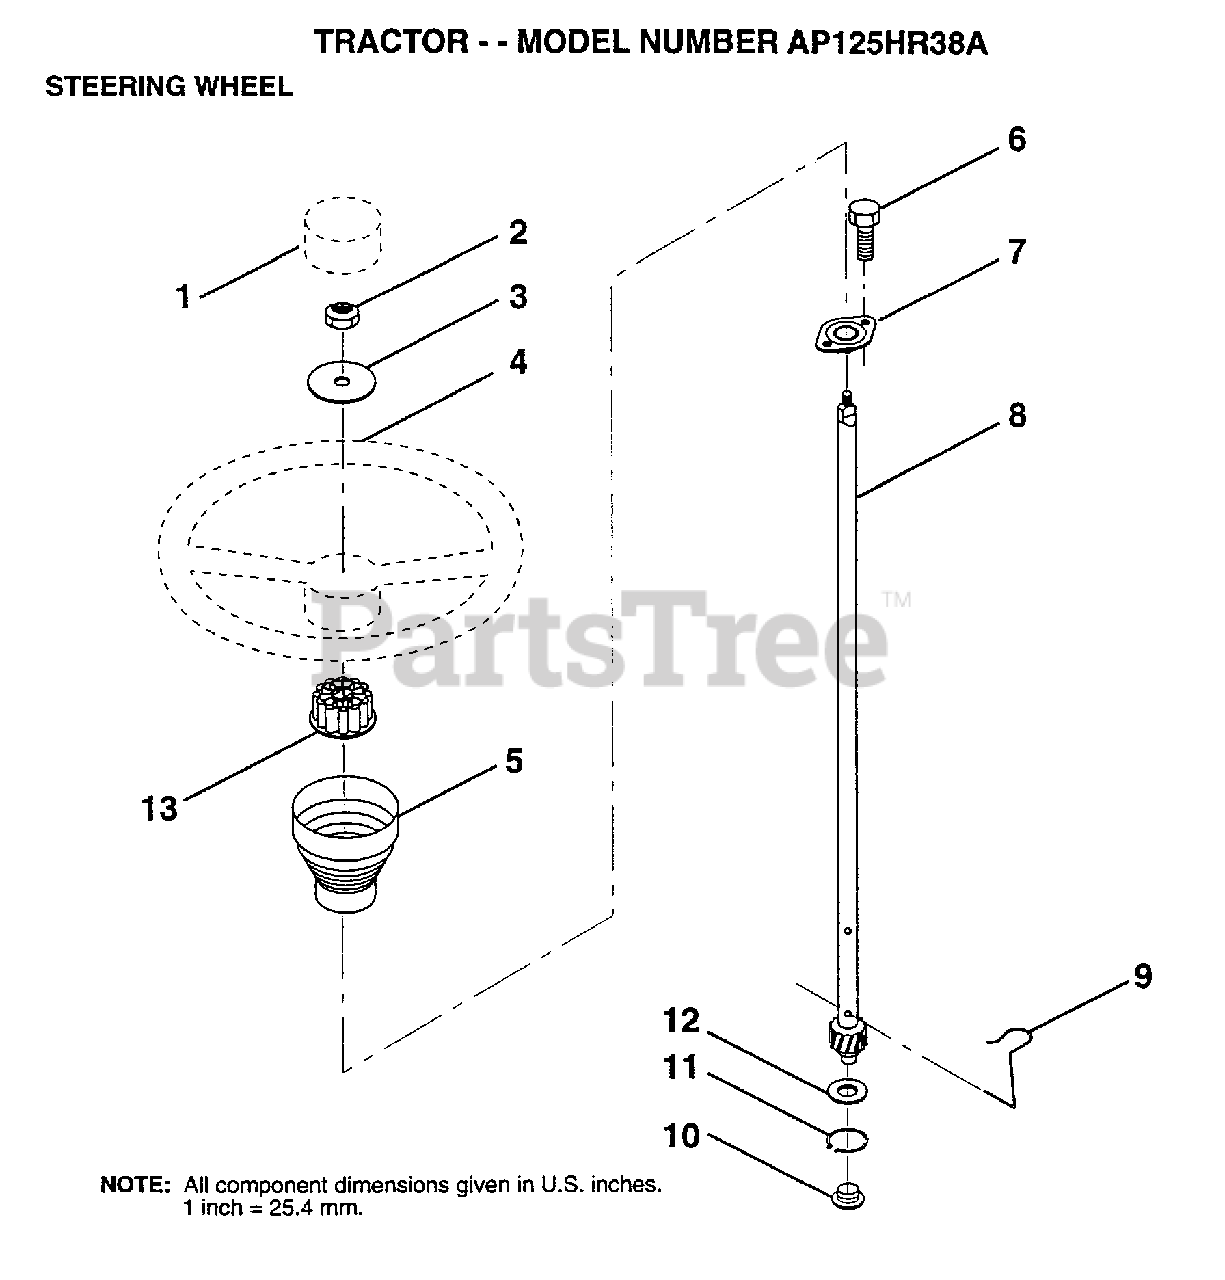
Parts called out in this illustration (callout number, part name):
1	CAP STEER AYP
2	GRIPCO NUT
3	WASHER T
4	WHEEL STR AYP BLK
5	SLEEVE STEERING
7	CABLE GUIDE TI
9	STEERING CLIP
10	BUSHING STEER LWR
11	RING
12	WASHER LT
13	ADAPTER-WHEEL LT
